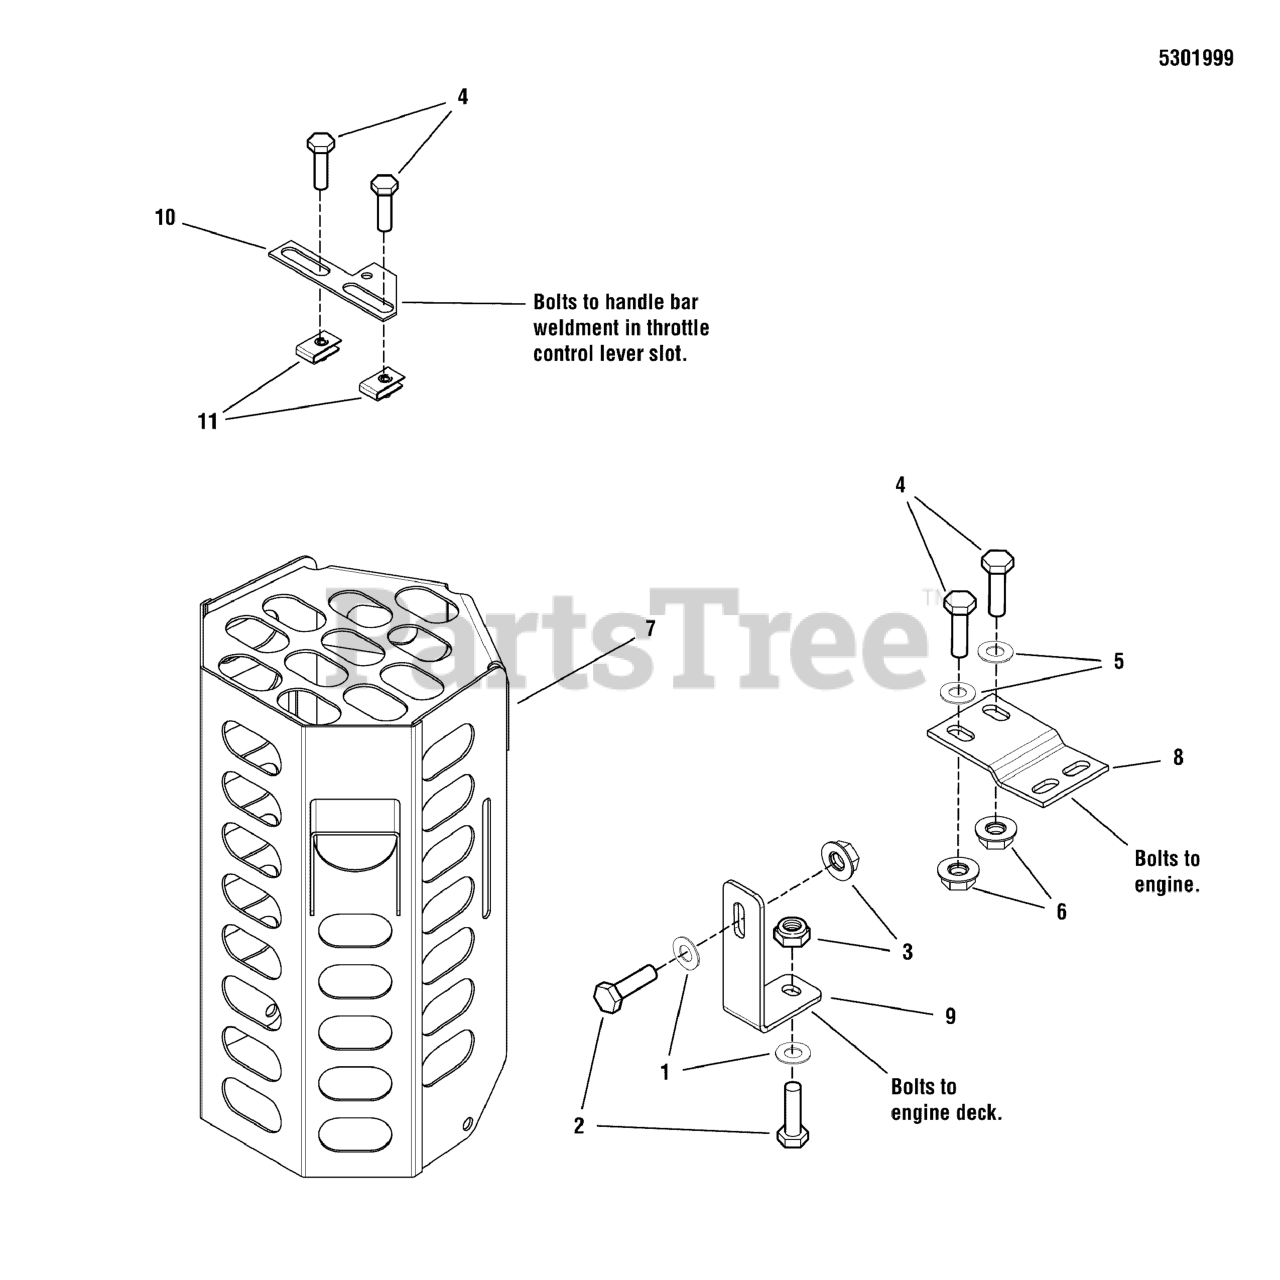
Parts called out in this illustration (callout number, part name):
1	WASHER, 5/16" SAE
2	BOLT, 5/16-18 X 3/4 GD5
3	NUT, 5/16-18 HEX NYLON LOCK
4	BOLT, 1/4-20 X 3/4 GD5 YZ
5	WASHER, 1/4 SAE
6	NUT, 1/4-20 HEX NYLON LOCK
7	WELD, MUFFLER GUARD, MUFFLER - RED
8	BRACKET, GUARD MOUNT, UPPER - RED
9	BRACKET, GUARD MOUNT, LOWER - RED
10	PLATE, THROTTLE STOP
11	BODY CLIP, 1/4-20 X 1/2 DEEP
